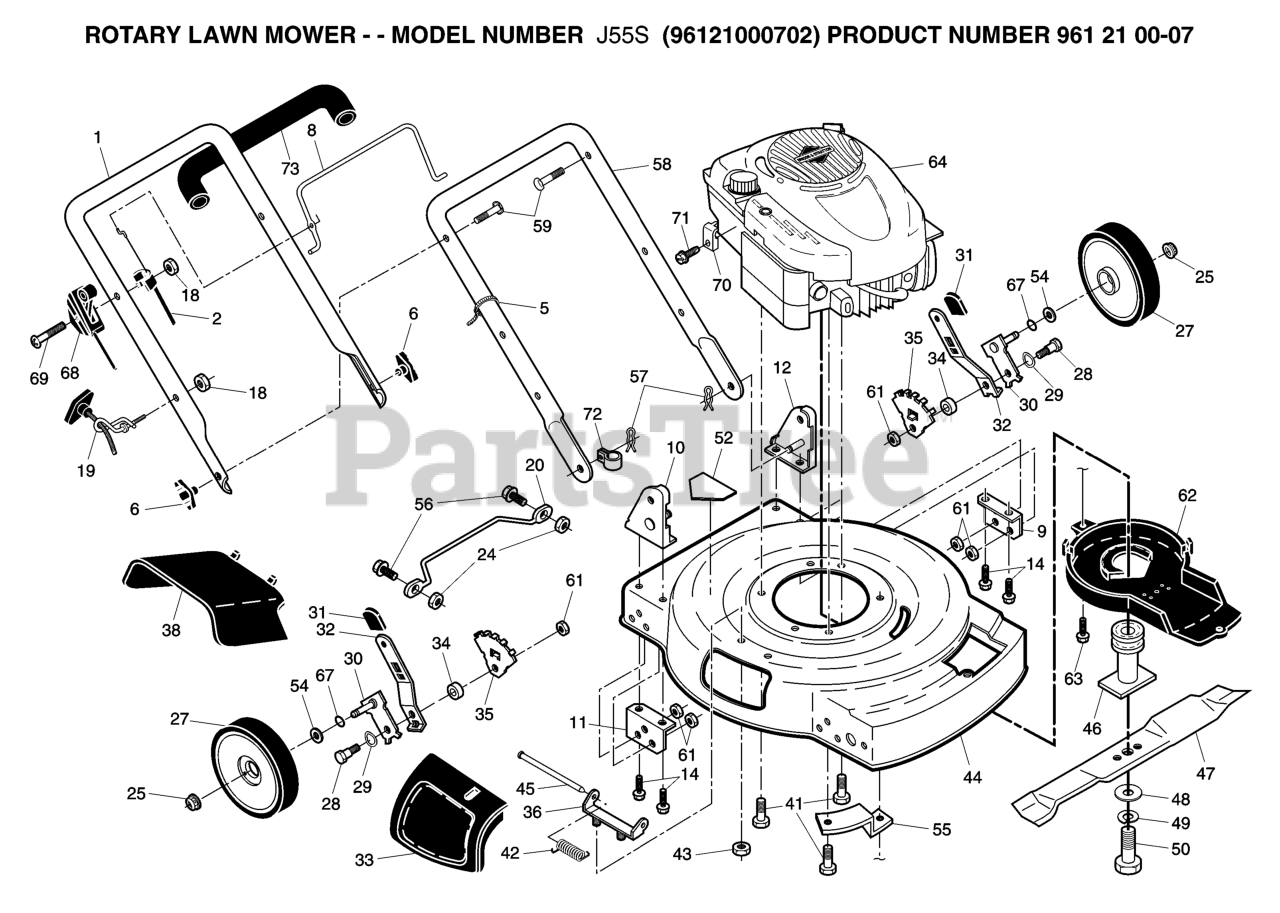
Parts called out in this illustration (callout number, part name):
1	HANDLE.UP.DLX.COMF.W/GRIP.GREY
2	ENGINE ZONE CONTROL CABLE
5	TIE GUIDE
6	KNOB, DEFLECTOR
8	BAIL.COMF.FWGD.668.ORANGE.WALK
9	GUARD.SLKSCR.BELT.
10	HANDLE BRACKET ASM. RH
11	Support Bracket, Handle, RH
12	HANDLE BRACKET ASM. LH
14	SCREW.5/16-18X3/4
18	NUT
19	RB GUIDE.ROPE.STD.BLK.ZIN WSL
25	NUT.HEX.FLANGE.3/8-16.LO(3 2)
27	WHEEL & TIRES ASSY, FRONT
28	BOLT
29	WASHER.CURVED.CYLINDRICAL
30	AXLE ARM ASSY.
31	SELECTOR KNOB
32	SPRING.SEL.EXT.21.DOMED.12/14
33	DOOR.MULCH.22.EZ.MULCH.GREY
34	SPACER.HEIGHT.ADJUSTER
35	BRACKET.ADJ.WHEEL.5POS.ADS
36	BRACKET.ASM.HOUSING.EZ.MUL
38	DEFLECTOR.GUARD.22..EZ.MULCH
41	BOLT 3/8-16X1-1/8
42	TORSION SPRING
43	LOCKNUT.NYLOC.1/4-20
44	Kit, Mower Housing
45	ROD.HINGE.COMBI-C
46	BLADE ADAPTOR / PULLEY
47	Blade, 22"
48	WASHER,HARDEN
49	LOCKWASHER
50	SCREW, HEX HD 3/8-24 X 1-3/8
52	DECAL.INTERNATIONL.CUTFINGER
54	WASHER.FLAT.1/2
55	BRACKET
56	REPL BY 817 02 10-08
57	HAIRPIN COTTER
58	HANDLE
59	BOLT, HANDLE 5/16-18X1.75
61	LOCKNUT PM
62	DEBRIS SHIELD
63	SCREW.HEX.WSH
67	O-RING..070X.487.NEOPRENE
68	THROTTLE CONTROL
70	CABLE CLAMP(ENGINE)
71	SCREW.HEX.HEAD.WASHER.10-16
72	CLIP.CABLE.BLK
73	GRIP.HANDLE.FOAM
